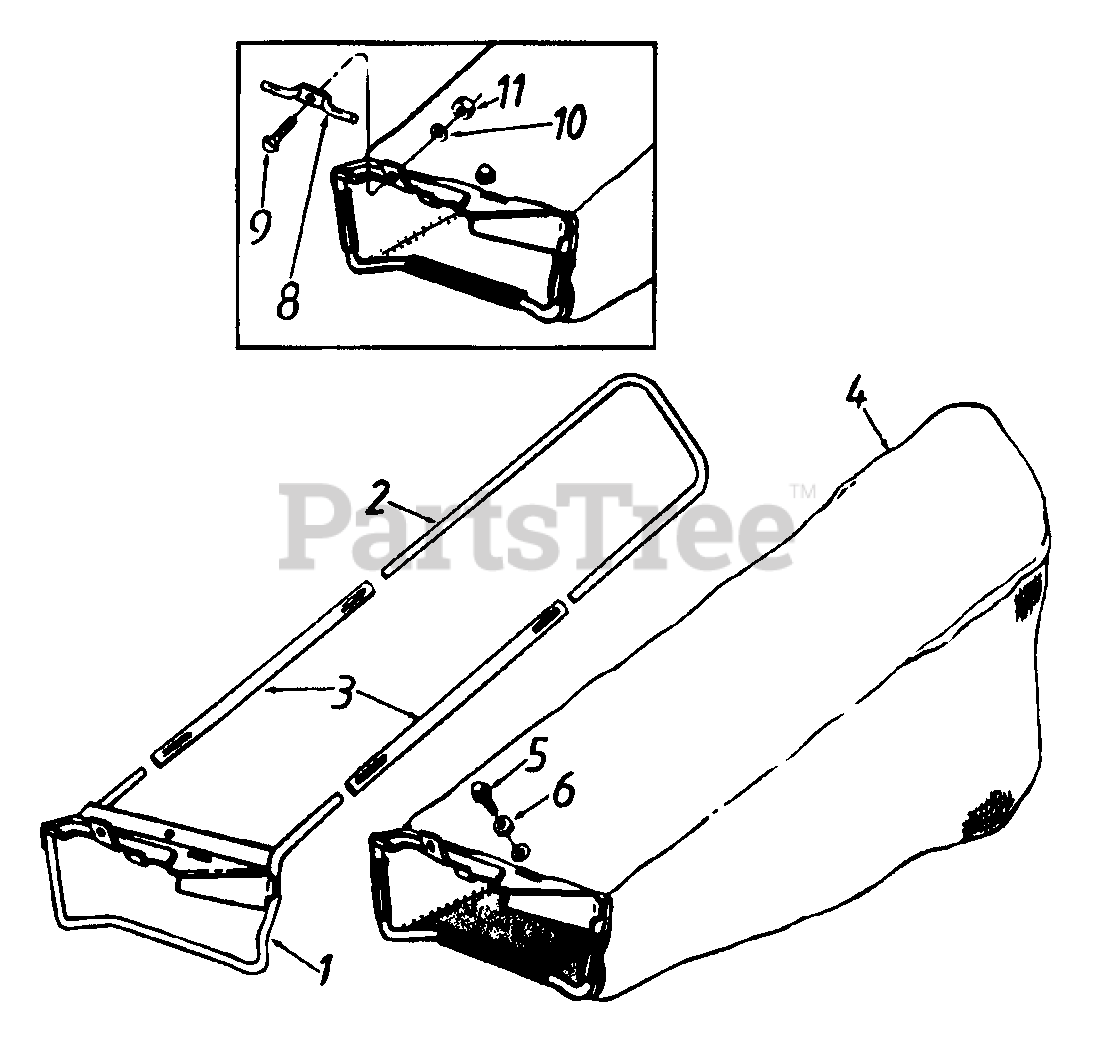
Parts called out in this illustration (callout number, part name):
4	Grass Bag
5	Hex Wash. Hd. TT-Tap Scr. 1/4-20 x 5' Lg.
6	Bell-Wash. 1/4" I.D
8	Grass Bag Hook
9	Hex Bolt 1/4-20 x .62" Lg.
10	L-Wash. 1/4" I.D.
11	Hex Nut 1/4-20 Thd.
